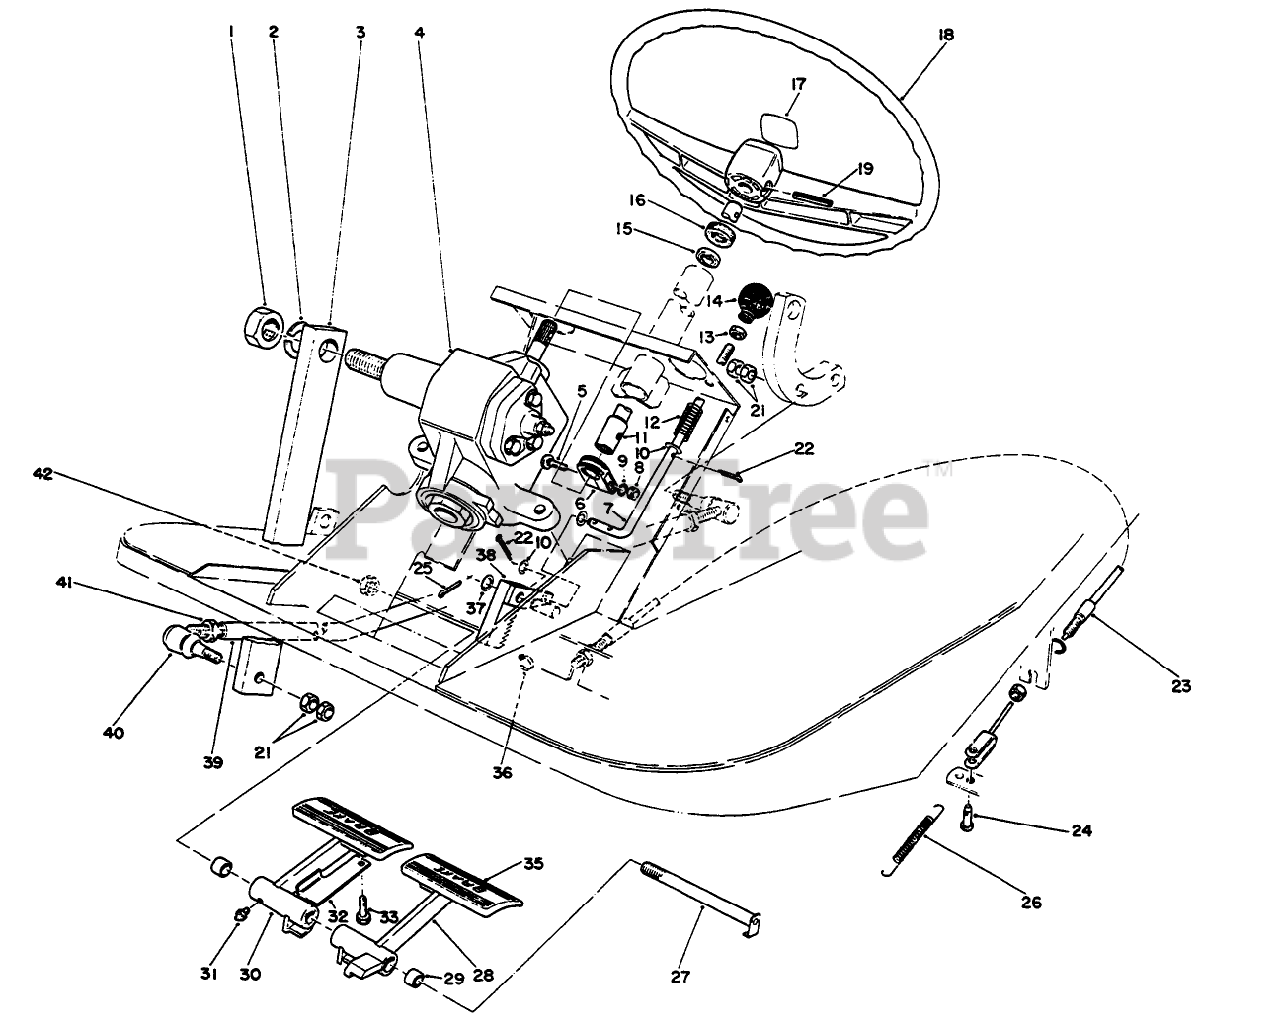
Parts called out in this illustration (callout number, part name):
1	NUT-JAM
2	WASHER-LOCK/SP
3	Pitman Arm
4	Steering Gear Assembly (Incl. Ref. #1 & 2)
5	7/16-14 X 1-3/4 BOLT
6	STRG COUPLING CLAMP
7	Rod Brake Latch
8	NUT-HEX
9	WASHER-LOCK
10	WASHER-FLAT
11	Shaft-Steering
12	Spring
13	NUT-HF
15	BALL BRG
16	COVER-DUST
17	Cap-Steering Wheel
18	WHEEL-STEERING
19	PIN-ROLL
21	NUT-HJ
22	PIN-COTTER
23	RH BRAKE CABLE ASM
24	PIN-CLEVIS
25	PIN-COTTER
26	SPRING-EXTENSION
27	Pin
28	Pedal-Brake L.H. (Incl. Ref. #29 & 31)
29	BUSHING
30	Pedal-Brake, R.H. (Incl. Ref. 29 & 31)
31	FITTING-GREASE
32	Latch Parking Brake
33	SCREW-HWH
35	PAD-BRAKE
36	TIE-CABLE
37	WASHER-FLAT
38	Rack
39	FRONT STEERING TUBE B
40	RH BALL JOINT ASM
41	NUT-JAM
42	NUT-LOCK, NI
